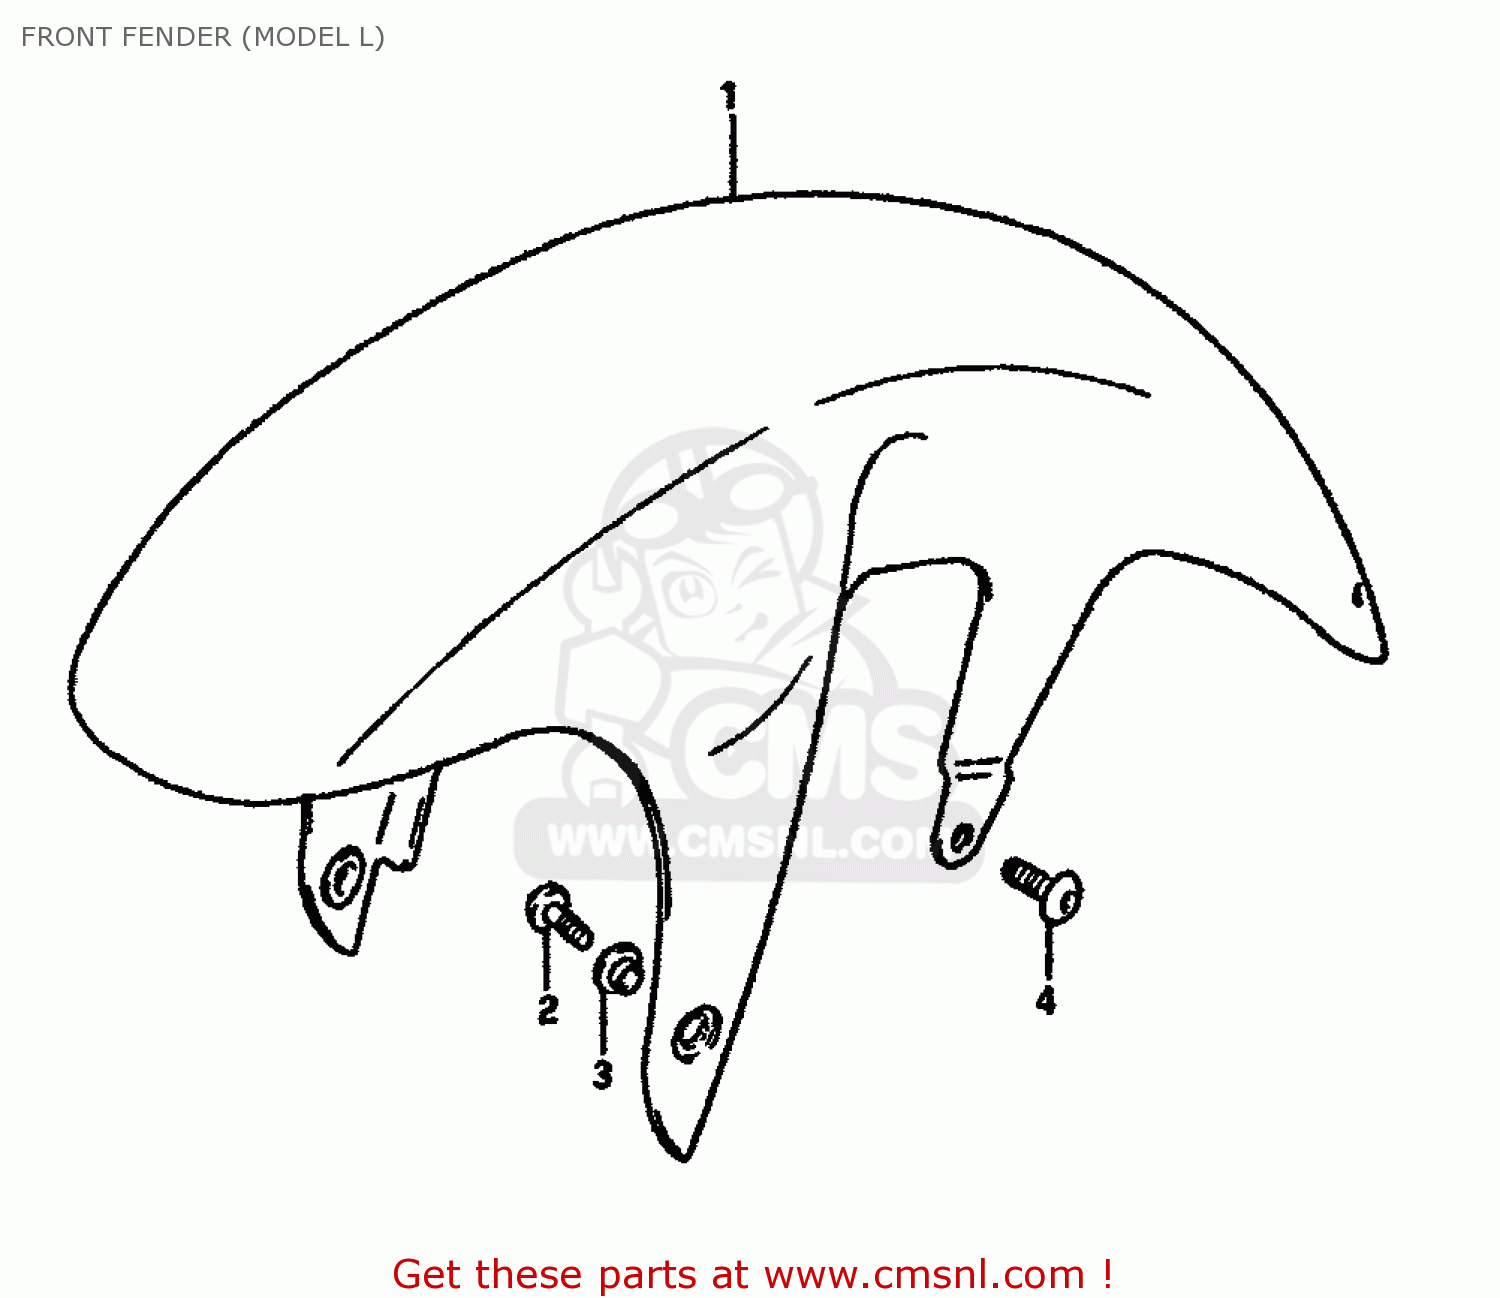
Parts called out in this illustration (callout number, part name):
1	FENDER,FRONT
2	SCREW(6X16)
3	WASHER(6.3X16X1.5)
4	SCREW(8X16)
5	CUSHION,FRONT FENDER
6	SCREW(8X16)
7	MUD GUARD,UPPER
8	SCREW, FRONT & REAR
9	WASHER
10	NUT 5MM
11	MUD GUARD,FR.F
12	MUD GUARD,FR.F
13	WASHER
14	WASHER
15	NUT 5MM
